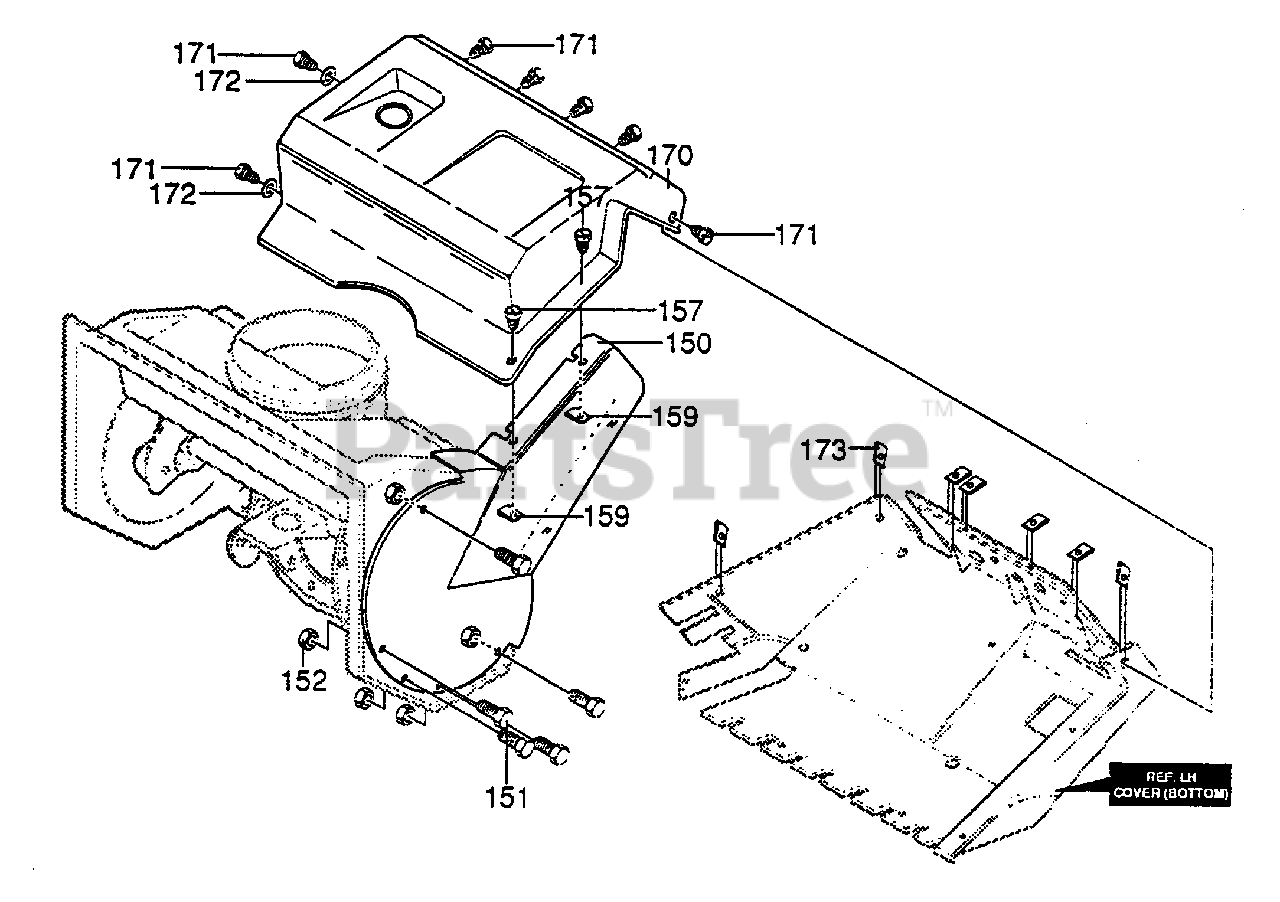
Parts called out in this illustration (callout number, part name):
150	COVER, BELT
151	SCREW, 10-24 X .50
152	NUT, #10-24
157	SCREW, 1/4-14 X .75
159	NUT, 1/4-10
170	COVER, TOP
171	SCREW, 1/4-14 X .75
172	FLATWASHER .281 X .63 X .065
173	NUT, 1/4-10
